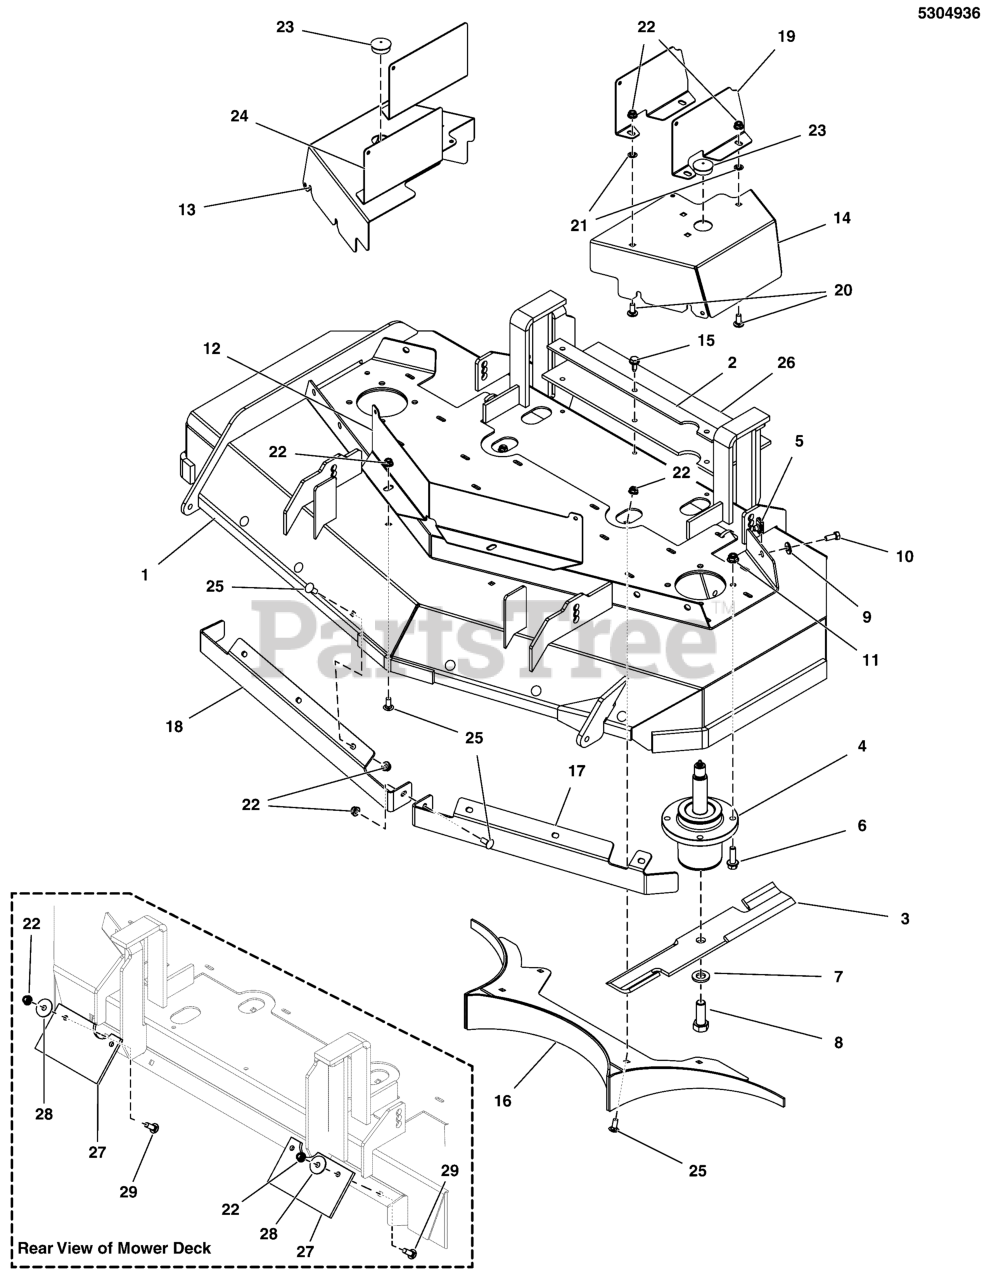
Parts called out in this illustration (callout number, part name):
1	DECK SHELL W/DECALS, Z148RDCE (5415509B)
3	BLADE SET, 48 DECK
4	ASSM, SPINDLE, LONG S
5	BODY CLIP, 5/16-18 X
6	BOLT, 3/8-16 X 1-1/4, FLANGE, GD 5, CZ
7	WASHER, BLADE BOLT, 9/16" F436, CZ
8	BOLT, 5/8-11 X 1-3/4 GD8
9	WASHER, 5/16 F436 FLAT
10	BOLT, 5/16-18 X 3/4 GD5
11	NUT, 3/8-16 HEX NYLOCK FLANGE
12	GUARD, Center
13	GUARD, LH
14	GUARD, RH
15	SCREW-HEX WSHR HD TAPTT5/16-18X0.750
16	BAFFLE, Rear
17	BAFFLE, DISCHARGE
18	BAFFLE, DISCHARGE
19	PLATE, Cover, Left
20	RHSSNB,5/16-18 X 3/4 GR5 ZINC/CLEAR
21	5/16 PUSH-ON NUT RETAINER, STL, CZ
22	NUT, 5/16-18 HEX NYLOCK FLANGE
23	PLUG, PANEL, 1.25 - BLACK
24	GUARD, Top
25	BOLT, 5/16-18 X 3/4, CARRIAGE, GD5, CZ
28	WASHER, 5/16 FENDER
29	BOLT, 5/16-18 X 1, CARRIAGE, GD5, CZ
